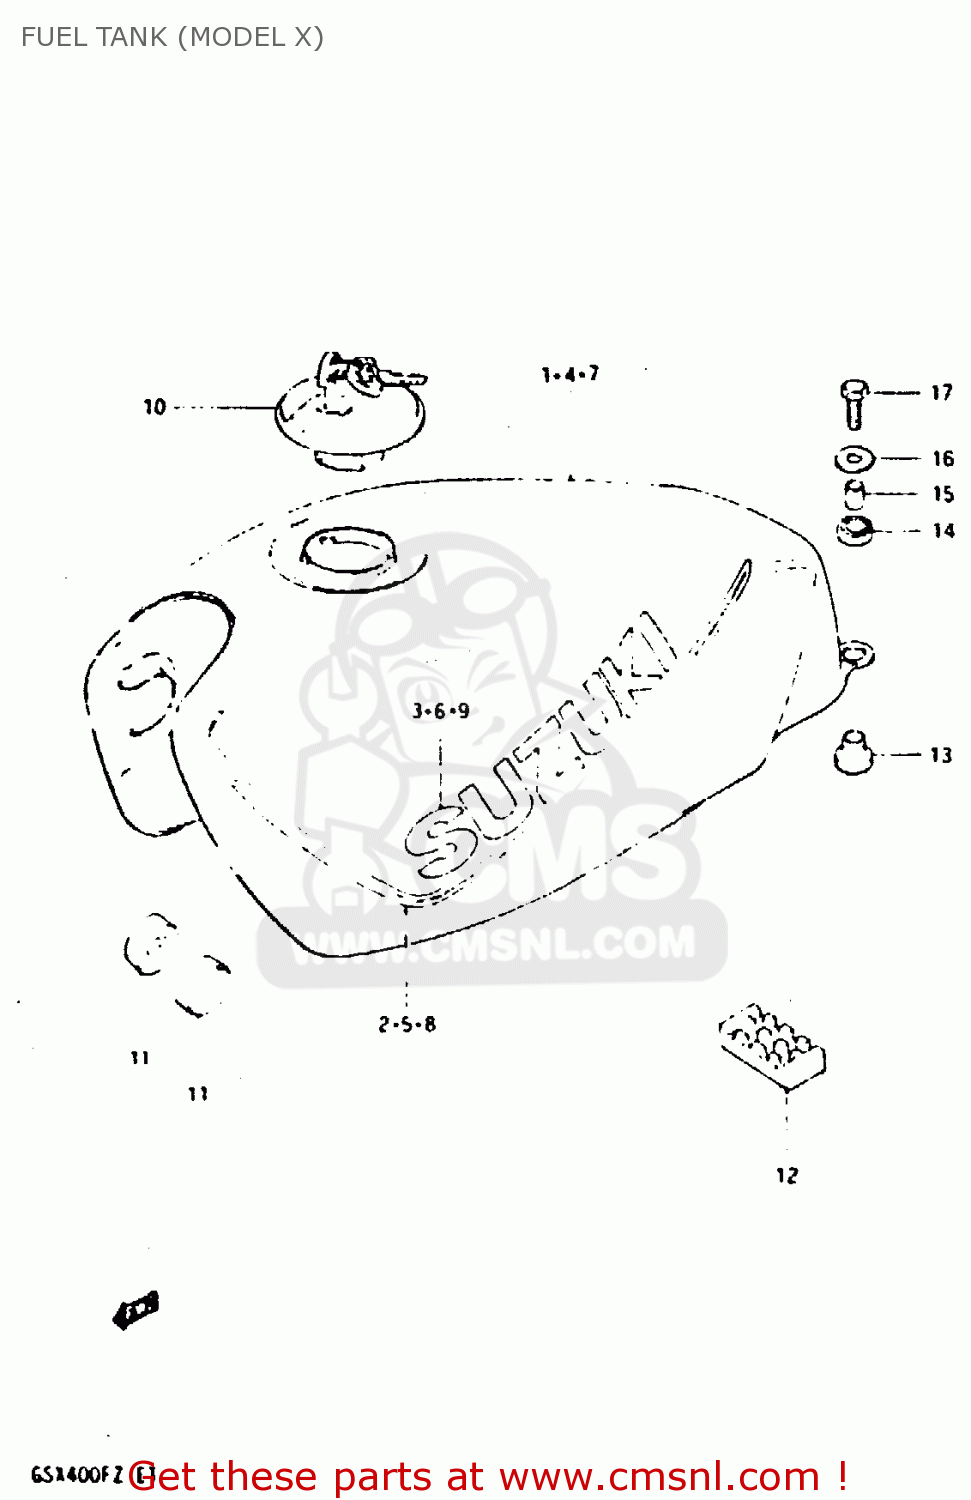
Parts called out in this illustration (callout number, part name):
1	TANK, FUEL (BLUE)
2	TAPE SET
3	EMBLEM,FUEL TANK
4	TANK, FUEL (SILVER)
5	TAPE SET
6	EMBLEM(ORANGE)
7	TANK, FUEL (RED)
8	TAPE SET
9	EMBLEM,FUEL TANK
10	CAP SET,FUEL TANK
11	CUSHION
12	CUSHION,FUEL TANK CTR
13	CUSHION
14	CUSHION
15	SPACER
16	WASHER (6.5X24X1.6)
17	BOLT
